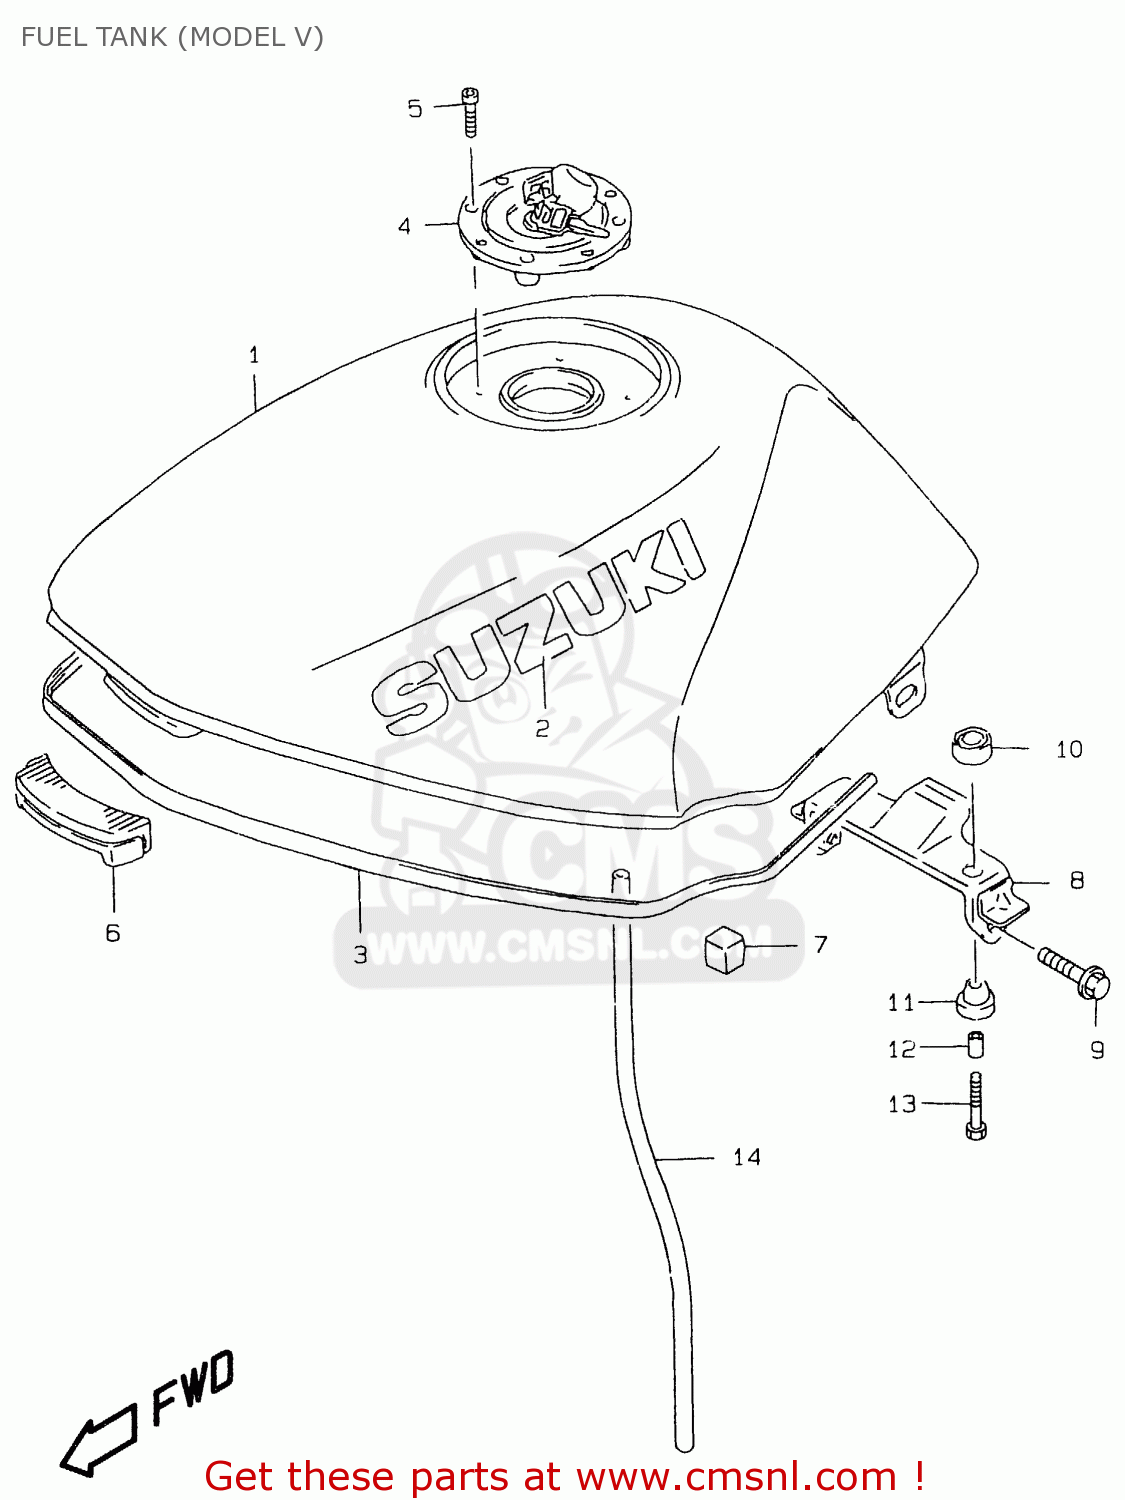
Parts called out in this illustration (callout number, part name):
1	TANK,FUEL (E22
2	EMBLEM,FUEL TANK
3	MOLDING
4	CAP SET,FUEL TANK
5	BOLT(5X20)
6	CUSHION,FUEL TANK FR
7	CUSHION,FUEL TANK SIDE
8	BRACKET COMP,FUEL TANK
9	BOLT
10	CUSHION
11	CUSHION
12	SPACER(6.5X9X18)
13	BOLT(6X30)
14	HOSE,WATER DRAIN
